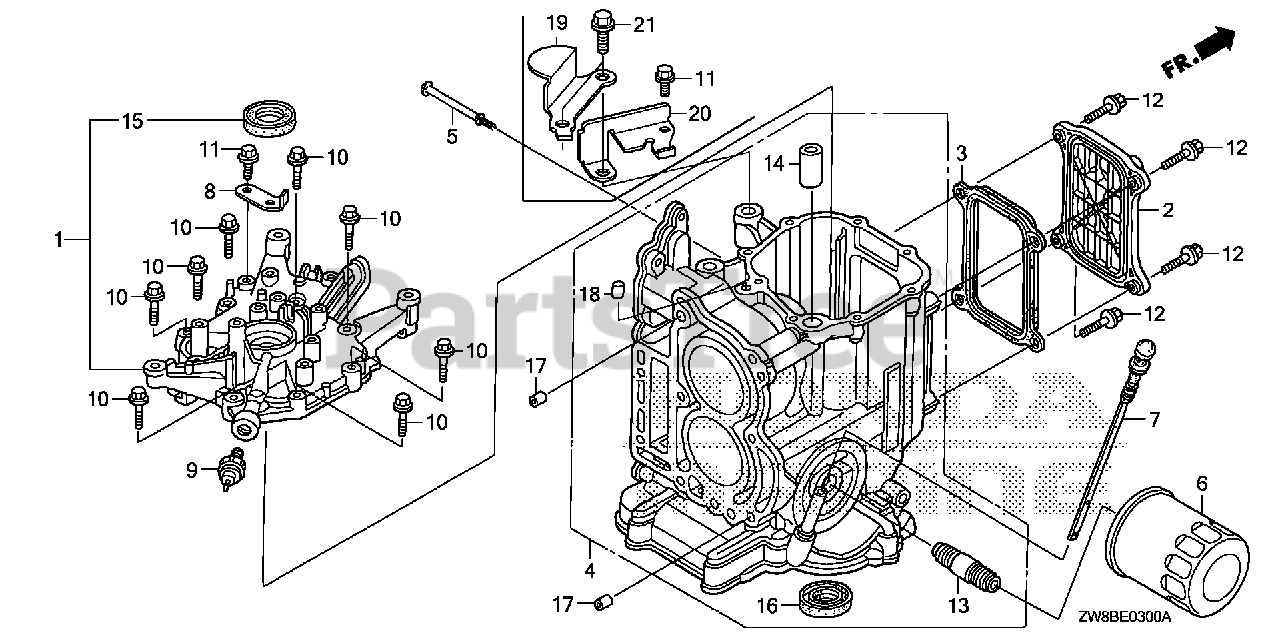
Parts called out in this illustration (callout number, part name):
1	COVER ASSY., CRANKCASE (000)
2	COVER, CRANKCASE SIDE
3	GASKET, CRANKCASE SIDE COVER
4	BLOCK ASSY., CYLINDER (000) *NH8* (DARK GRAY)
5	STOPPER, ENGINE SIDE
6	FILTER, OIL (TOYO ROKI)
6	FILTER, OIL (DENSO)
7	DIPSTICK, OIL
8	STAY D, ENGINE WIRE HARNESS
9	SWITCH ASSY., OIL PRESSURE
10	BOLT, FLANGE (6X28)
11	BOLT, FLANGE (6X14) (CT200)
12	BOLT, FLANGE (6X22) (CT200)
13	HOLDER, OIL FILTER
14	PIN, DOWEL (14X20)
15	OIL SEAL (30X42X7)
16	OIL SEAL (26X45X7)
17	PIN, DOWEL (10X12)
18	PIN B, DOWEL (8X14)
19	PLATE A, FLYWHEEL COVER
20	PLATE B, FLYWHEEL COVER
21	BOLT, FLANGE (8X25)
